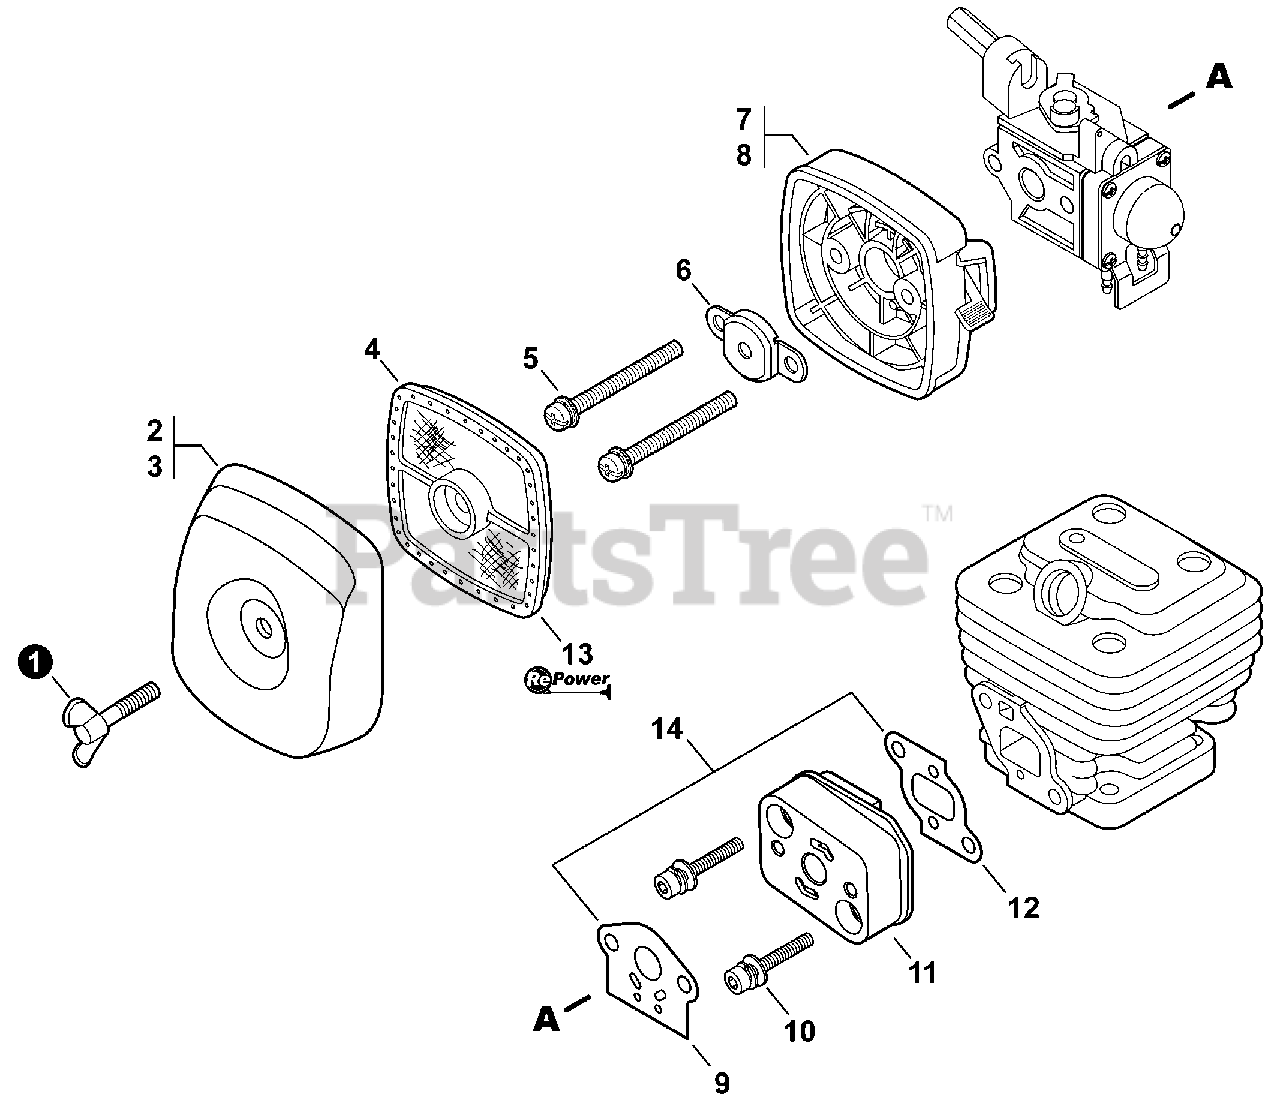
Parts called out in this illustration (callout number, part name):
1	BOLT, WING 5×20
2	COVER, AIR FILTER - GRAY
3	COVER, AIR FILTER - BLACK
4	FILTER, AIR - DOUBLE LAYER
5	SCREW 5×60
6	PLATE, PREVENT
7	CASE, AIR FILTER - GRAY
8	CASE, AIR FILTER - BLACK
9	GASKET, CARBURETOR
10	BOLT 5×25
11	INSULATOR, INTAKE
12	GASKET, INTAKE
13	TUNE-UP KIT - REPOWER
14	GASKET KIT
